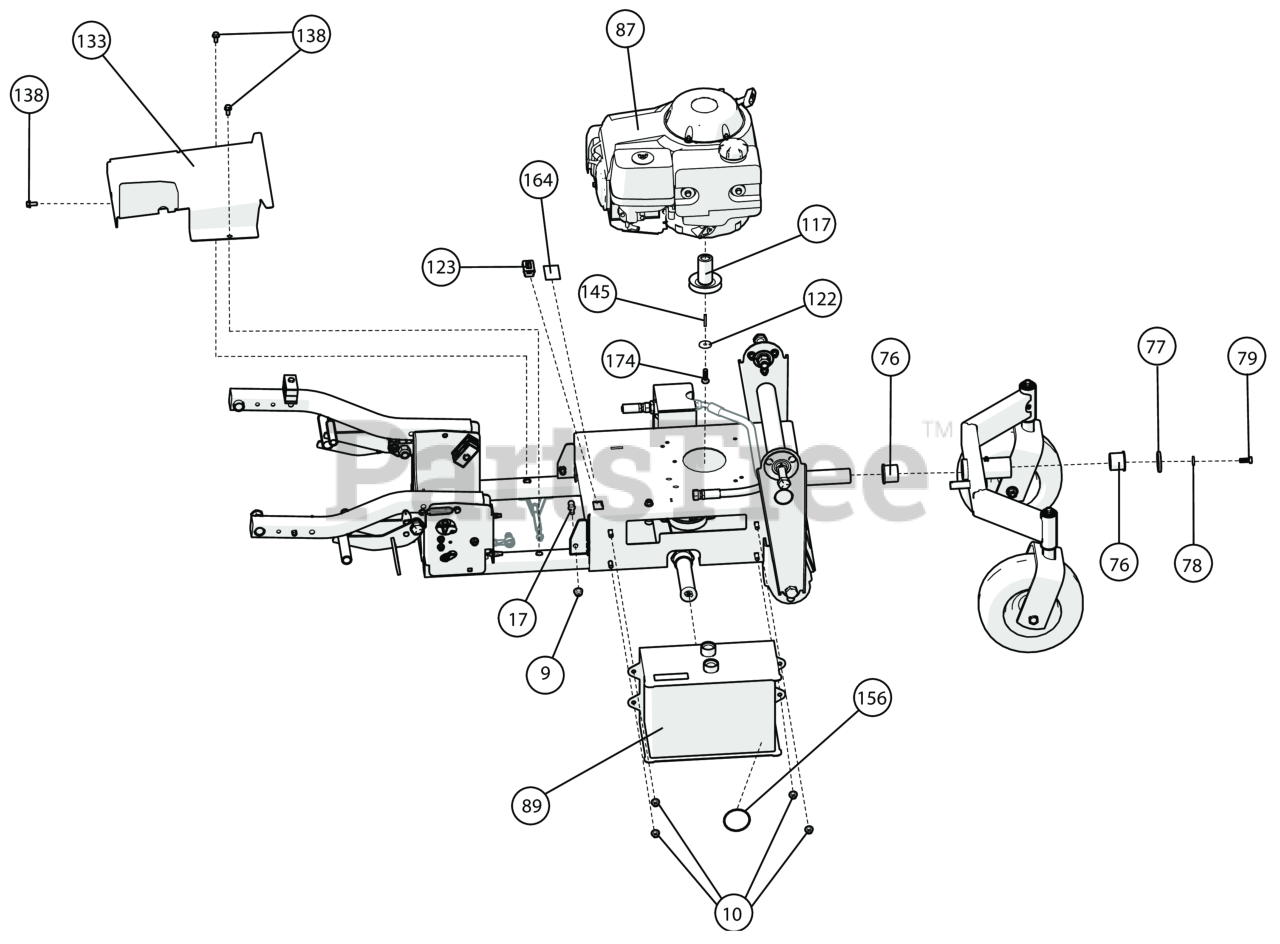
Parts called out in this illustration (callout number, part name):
9	NUT-HEX-NYLK, FLG .3125-18 ZP
10	NUT-HEX-NYLK, FLG .375"-16 ZP
17	BALL STUD, 1/2" X 5/16-18 ZP
76	BUSHING 1.500 ID X 1.5 LONG FLANGED
77	WASHER DECK RETAINING
78	WASHER LOCK 3/8" S/T MED
79	SCREWCAP 3/8"-24 X 1" HCS GR 8
87	ENGINE 13HP HONDA GX390UTQA2
89	WA, TANK, HYDRAULIC, 3 GAL
117	PULLEY, 4.00"
122	WSHR-STL,BLV, .450"X1.500"X.172" MZ
123	HOURMETER, INDUCTIVE PANEL MOUNT
133	SHIELD, TRANSAXLE
138	SER HEX WASHER FLNG SCREW 5/16"-18 X 3/4"
145	KEY SQUARE 1/4" X 1"
156	LABEL DECAL SM CIRCLE
164	DECAL, WARNING, HAND IN BELT, ENG. ONLY
174	SCREWCAP 7/16-20 X 1 1/2 GR 8 W/PATCH
